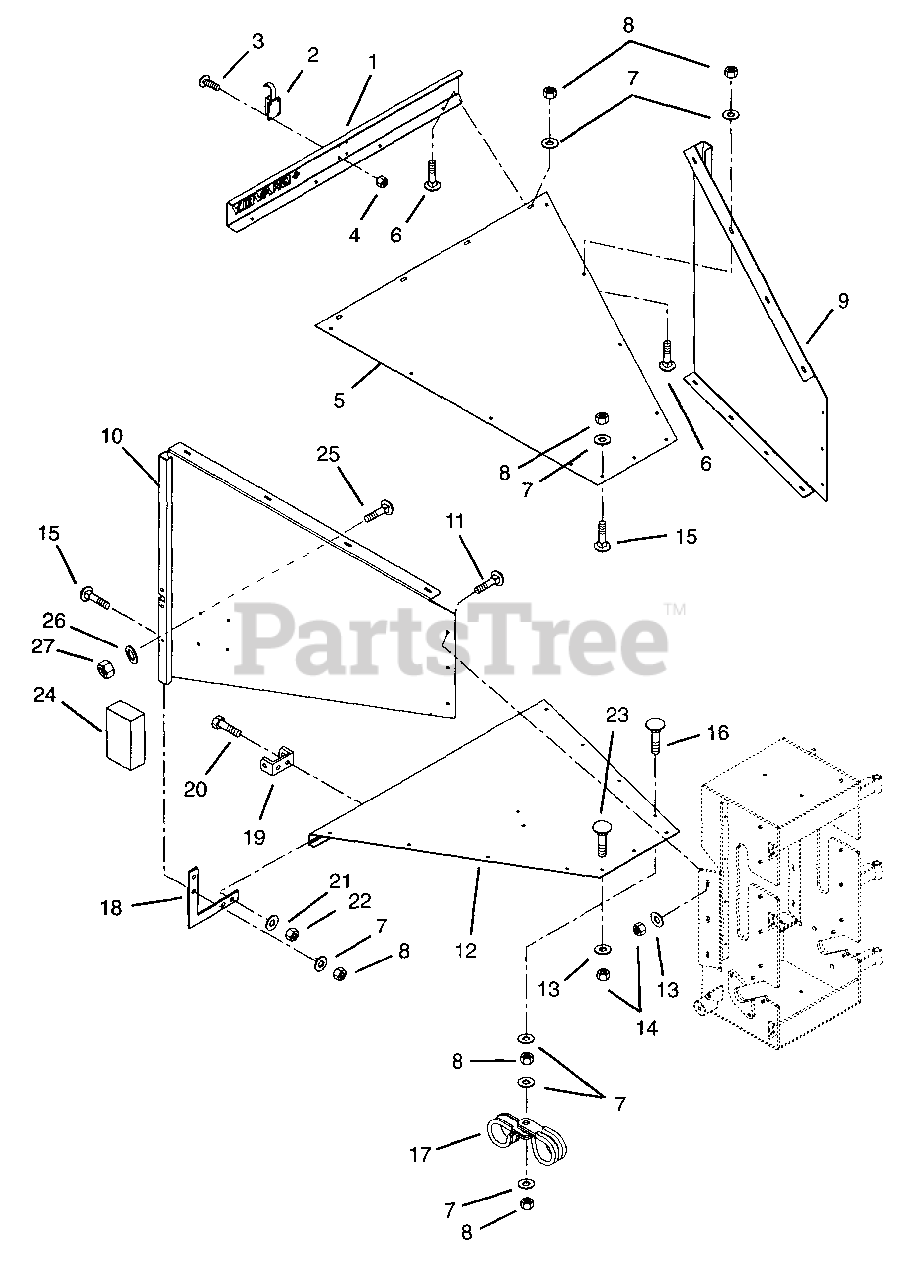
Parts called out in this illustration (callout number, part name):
1	Hopper Safety Tab
3	Screw-Machine 10-24 x .50
4	Nut-Locking-Nylon 10-24 w/Insert
5	Hopper Top
6	Bolt-Round Head Square Neck .31-18 x .75
7	Washer-Flat-Steel .38 x .875 x .083
8	Nut-Locking .375-16
9	Hopper-Left Hand Side
10	Hopper-Right Hand Side
11	Bolt-Round Head Square Neck .50-13 x 1.25
12	Hopper Bottom
13	Washer-Flat-Steel .563 x 1.38 x .109
14	Nut-Locking-Center .50-13
15	Bolt-Round Head Square Neck .38-18 x 1.00
16	Bolt-Round Head Square Neck .38-18 x 1.25
17	Clamp-Steel 1.0
18	Reinforcement-Hopper Corner
19	Hinge-Apron
20	Bolt-Hex .38-16 x 1.25 Grade 5
21	Washer-Flat-Steel .438 x 1.00 x .083
22	Nut-Locking-Center .38-16
23	Bolt-Round Head Square Neck .50-13 x 1.00
24	Box-Literature
25	Bolt-Round-Head-Square-Neck .25-20 x .50 Grade 5
26	Washer-Flat-Steel .312 x .734 x .065
27	Nut-Locking Center .25-20
